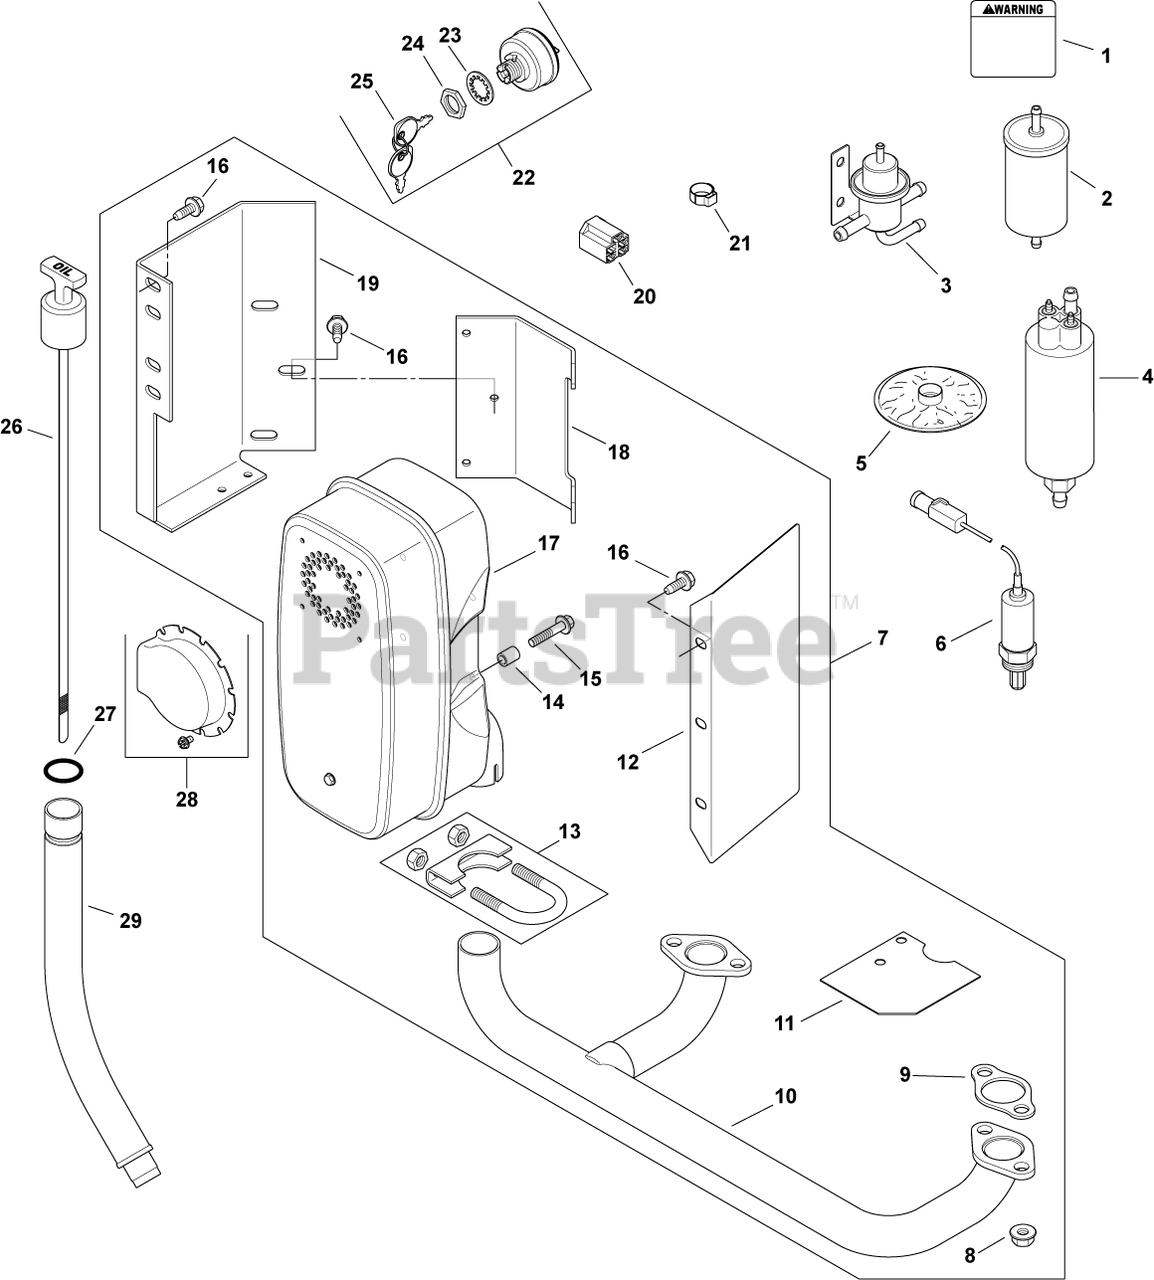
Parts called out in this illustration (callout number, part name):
1	DECAL, WARNING
2	FILTER, FUEL
3	REGULATOR ASSY, FUEL PRESSURE
4	PUMP ASSY, FUEL-USE 24 393 52-S
5	FILTER, FUEL STRAINER
6	SENSOR, OXYGEN
7	KIT, MUFFLER MOUNTING
8	NUT, FLG M8X1.25
9	GASKET, EXHAUST
10	MANIFOLD, EXHAUST
11	DEFLECTOR, HEAT
12	DEFLECTOR, EXHAUST
13	CLAMP, MUFFLER
15	SCREW, FLG M6X1.0X30
16	SCREW,FLG THD FRM M6X1.0X16-(#25086397S)
17	MUFFLER USE 24 067 127-S
18	BRACKET, MUFFLER
19	BRACKET, MUFFLER
20	CONNECTOR
21	CLAMP, FUEL HOSE
22	SWITCH, ASSEMBLY, KEY
23	WASHER, INTERNAL TOOTH
24	NUT, KEY SWITCH
25	KEY, SET -USE 48 340 01-S
28	KIT, MUFFLER DEFLECTOR-USE 24 755 168-S
29	TUBE, OIL FILL
